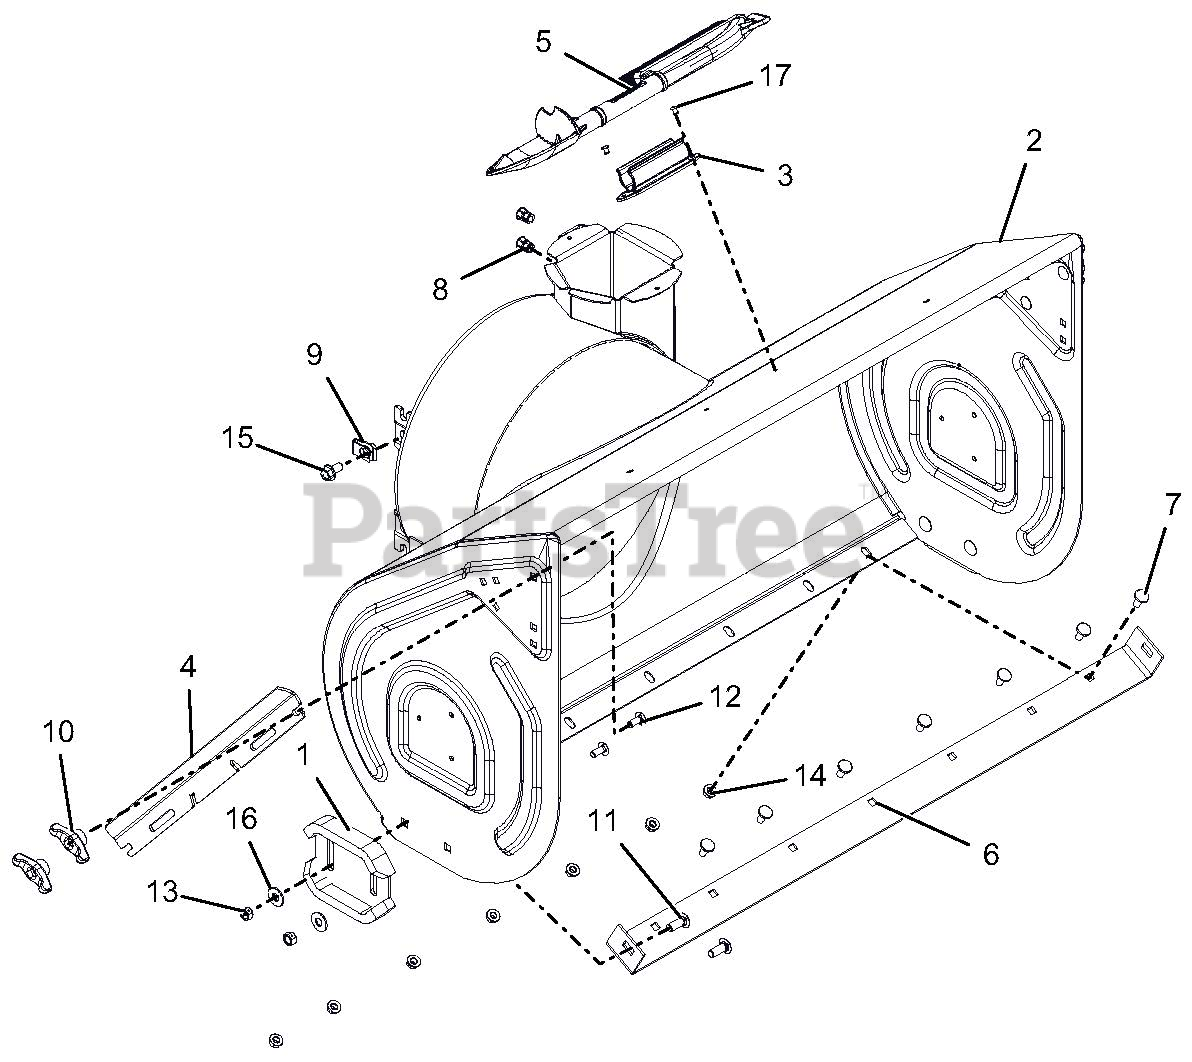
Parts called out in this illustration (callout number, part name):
1	RUNNER, SKID SHOE
2	BLOWER HOUSING W/DECAL 36"
3	MOUNT, SNOW CLEAN OUT
4	CUTTER, DRIFT
5	DEVICE, SNOW CLEAN OUT W/BRUSH
6	BLADE, SCRAPER-36"
7	BOLT, MODIFIED HEAD CARRIAGE
8	NUT, THREADED INSERT .38-16
9	NUT-RTNR .375-16X.37
10	KNOB,WING .31-18 UNC NYL/TALC
11	@BLT-RDHDSHSQNK.38-16X1.0 G5YZ
12	@BLT-RHDSSQNK .31-18X.75 G5YZ
13	@NUT-LK-CTR .38-16 YWZC
14	@NUT-LK-TOP-FLG .31-18 YWZC
15	BLT-SERHFWH .38-16X.75 YWZC
16	@WSHR-FL-STL.438X1.00X.083 YWZ
17	RVT-POP .187 YZ
